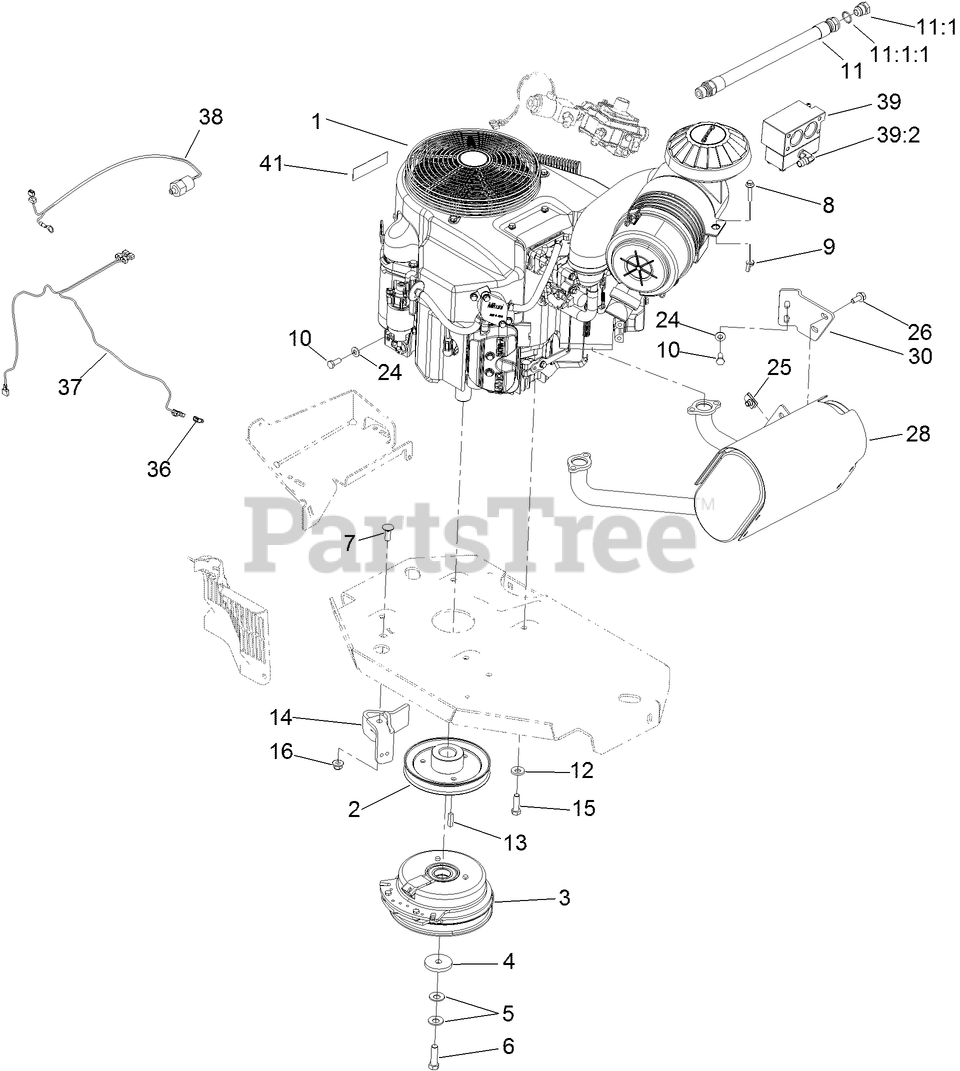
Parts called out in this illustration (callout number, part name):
2	SHEAVE
3	CLUTCH KIT
4	WASHER-CLUTCH
5	WASHER-SPRING
6	SCREW-HH, W/LOCTITE
7	SCREW-CARR
8	SCREW-HHF
9	NUT-WING
10	SCREW-HH
11	ENGINE OIL DRAIN HOSE ASM
11:1	PLUG-HH
11:1:1	O-RING
12	WASHER-BELLEVILLE
14	CLUTCH-ANCHOR
15	SCREW-HH
16	NUT-HF, NI
24	WASHER-SPRING
25	NUT-U
26	SCREW-HHF
28	MUFFLER
30	BRACKET-MUFFLER
36	TERMINAL-TAB
37	WIRE HARNESS
38	OIL PRESSURE SWITCH ASM
39	LPG MIXER ASM
41	DECAL-LPG ENGINE
